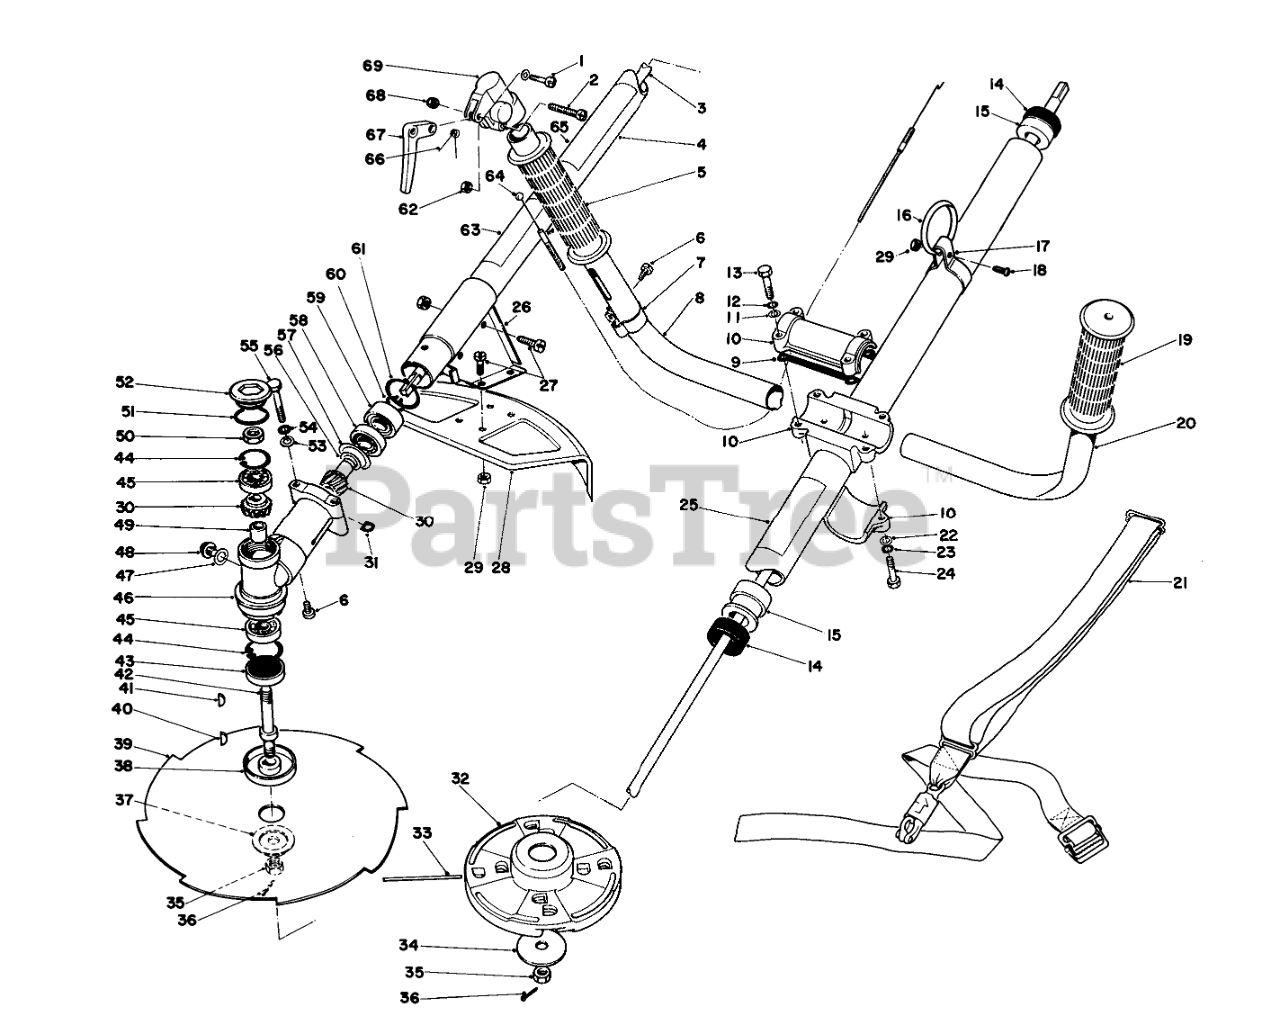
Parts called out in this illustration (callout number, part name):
1	Screw
2	Screw w/Washer
3	Shaft-Driving
4	Housing Drive Shaft (Incl. Ref. #25 & 26)
5	Right Hand Grip
6	SCREW
8	Handle R.H.
9	Spacer
10	Bracket Assembly, Handle (Incl. Ref. #9-13 & 22-24)
11	WASHER
12	Washer
14	Bushing
16	RING-HARNESS
17	HARNESS CLAMP
18	10-24 X 5/8 PAN HD MS
19	LH GRIP
20	Handle L.H.
21	Deluxe Harness
22	Washer
23	Washer
25	Decal
26	Bracket Shield
27	SCREW-PPH
28	Shield
29	NUT-LOCK, NI
30	Gear Set
31	Spacer
32	FIXED LINE CUTTER HD PK
33	Filament Line Pkg. (24 Pcs.)
34	WASHER
36	1/16 X 1 LG COTTER PIN
37	Blade Adapter Kit (Incl. Ref. #35 & 36)(optional)
38	Plate-Blade Fixing
39	Weed Blade
40	Woodruff Key
41	Woodruff Key
42	Shaft, Power Take Off
43	Oil Seal
44	Circlip
45	Ball Bearing
46	Housing Gear
47	Gasket
49	Spacer
51	O-Ring
52	Lid, Gear Housing
53	WASHER
54	Washer
56	Washer
57	Washer
58	Ball Bearing
59	Ball Bearing
60	Circlip
61	Circlip
62	Nut
63	Decal-TC800
64	Throttle Cabel
65	Decal Warning
66	Return Spring
67	THROTTLE LEVER
69	Bracket Throttle Trigger
